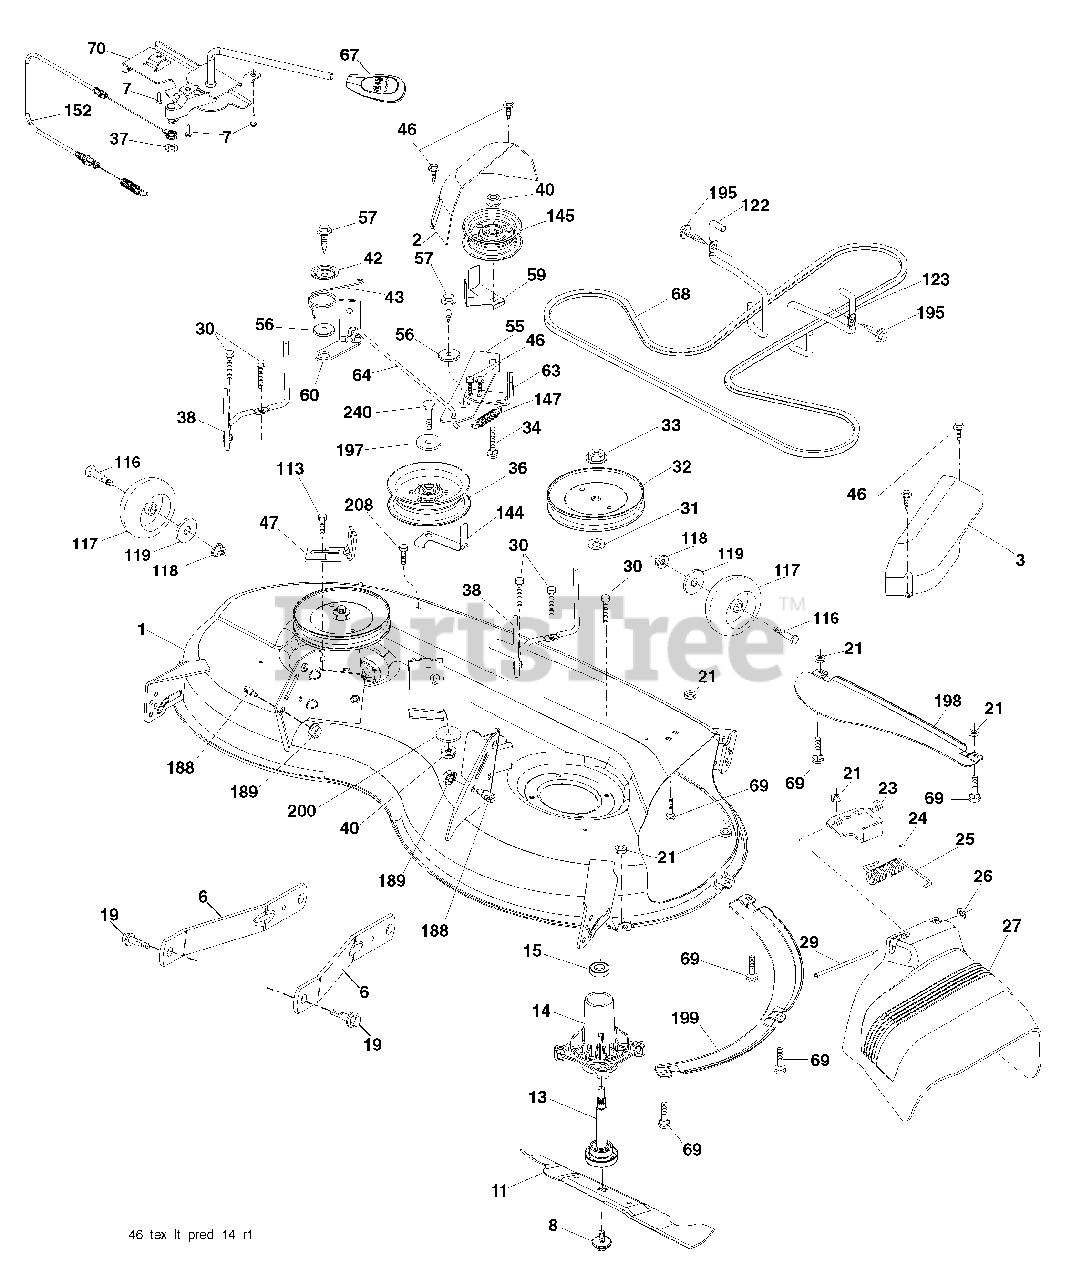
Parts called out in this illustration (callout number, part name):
1	Mower Housing
2	Cover Mandrel RH
3	Cover Mandrel LH
6	Arm Suspension
7	Screw #10 x 0.750 BOS Thread
8	Bolt/Washer asm 7/16-20 unf
11	Blade Mower
13	Shaft Assembly, Mandrel
14	Housing, Mandrel
15	Bearing, Ball, Mandrel
19	Bolt, Shoulder
21	Nut
23	Bracket, Deflector
24	Cap, Sleeve
25	Spring, Torsion, Deflector
26	Nut, Push
27	Shield, Deflector
29	Rod, Hinge
30	Screw Thdrol Rolling Wsh Hd
31	Washer, Spacer
32	Pulley, Mandrel
33	Nut, Toplock, Flanged
34	Bolt Carr Sh. 3/8-16 x 1-1/2 Gr. 5
36	Pulley, Idler, 4.50 RAW
37	Washer 13/32 x 13/16 x 16 Ga.
38	Keeper Belt LH Mandrel
40	Nut, Lock Flg. 3/8-16 unc
42	Spring Trosion Brake
43	Spring Torsion Retainer
46	Screw
47	Bracket Clutch Cable
55	Arm, Idler
56	Spacer, Retainer
57	Screw Hexwsh Thd 3/8-16 x 1
59	Guard, Tuv Idler (94)
60	Arm Brake Mower LH
63	Arm Brake Mower
64	Linkage Brake
67	Handle, Clutch Cable
68	V-Belt
69	Bolt
70	Clutch Asm.
113	Screw 5/16-18
116	Bolt, Shoulder
117	Wheel, Gauge
118	Nut Centerlock 3/8-16 unc
119	Washer 13/32 x 1-1/4 x 12 Ga.
122	Keeper Belt Eng. LH
123	Keeper Belt Eng. RH
144	Keeper Belt
145	Pulley Idler Primary
147	Spring Return
152	Cable Clutch Manual w/Spr.
188	Stud Fastener
189	Nut Lock Hex Flange
195	Screw 3/8-16 x 3/4
197	Washer 13/32 x 13/16 x 12 Ga.
198	Baffle Center Front
199	Baffle Front RH
200	Washer 13/32 x 1 x 1/2 11 Ga.
208	Screw Throl 3/8-16 x 1/2
240	Bolt 3/8-16 unc x 2-1/4 Gr. 5
240	Mandrel Assembly
240	Replacement Mower, Complete
